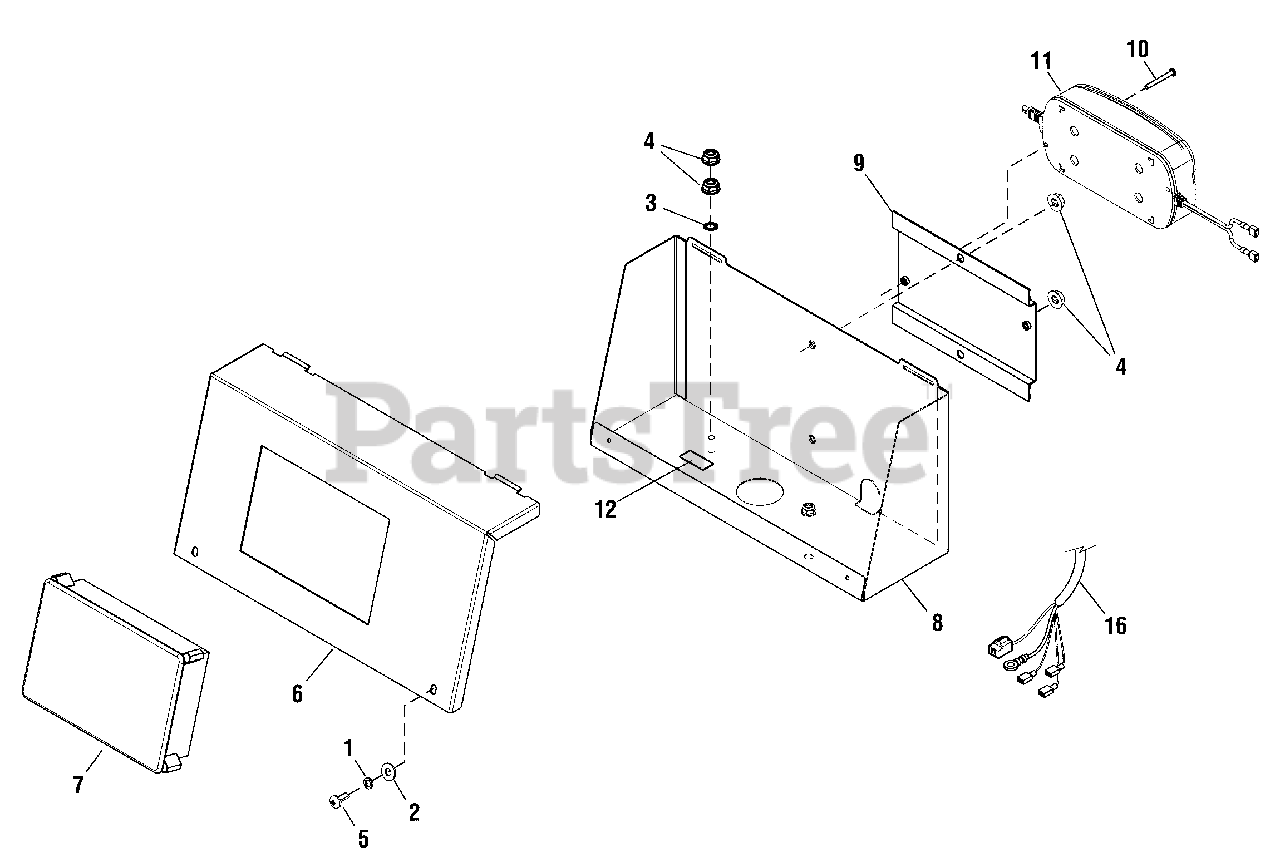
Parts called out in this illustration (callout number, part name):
1	* WASHER, Split Lock, #10
2	* WASHER, Flat, #10
3	* WASHER, External Lock, M6
4	* NUT, Nylock, 1/4-20
5	* SCREW, Phillips Head, Trilobular, #10-32 x 3/4
6	COVER-CONTROL PANEL
8	BOX-CONTROL PANEL
10	* SCREW, Phillips Head, 8-32 x 1-1/2
11	CHARGER-BATTERY
12	DECAL
